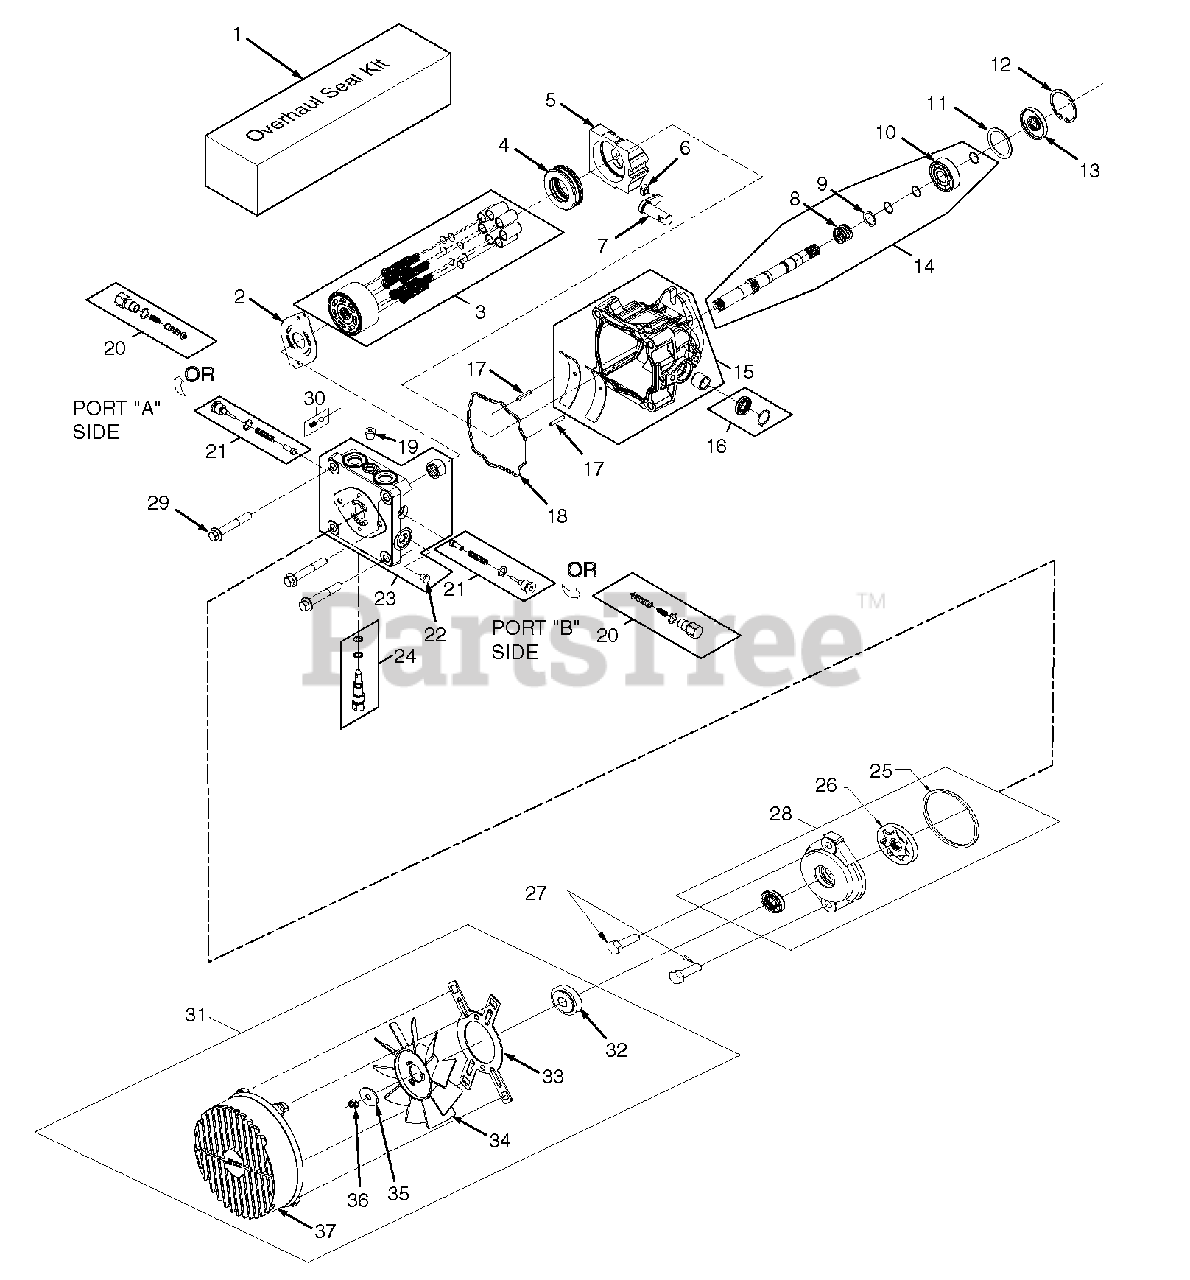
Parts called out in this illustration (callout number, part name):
1	Overhaul Seal Kit
2	Valve Plate
3	Cylinder Block Kit - 16cc
4	Thrust Ball Bearing Assembly
5	Variable Swashplate
6	Slot Guide
7	Trunnion Arm
8	Block Spring
9	Block Thrust Washer
10	Shaft Ball Bearing
12	Retaining Ring
14	Kit, Pump Shaft
15	Housing Kit
16	Trunnion Seal Kit
18	O-Ring
19	Straight Thread Plug
20	Shock Valve Kit (.031 Orifice)
21	Shock Valve Kit (.024 Orifice)
22	Straight Thread Plug
23	End Cap Kit
24	Bypass Valve Kit
26	Gerotor Assembly (.19 cu.in./rev.)
27	Socket Head Cap Screw (M8 x 1.25-25mm)
28	Charge Pump Kit (.19 STD. Splined)
29	Hex Screw, Flanged Head (M10 x 1.50-65mm)
30	Charge Relief Kit
31	Fan Kit
33	Bracket, Shroud
35	Washer
37	Shroud
